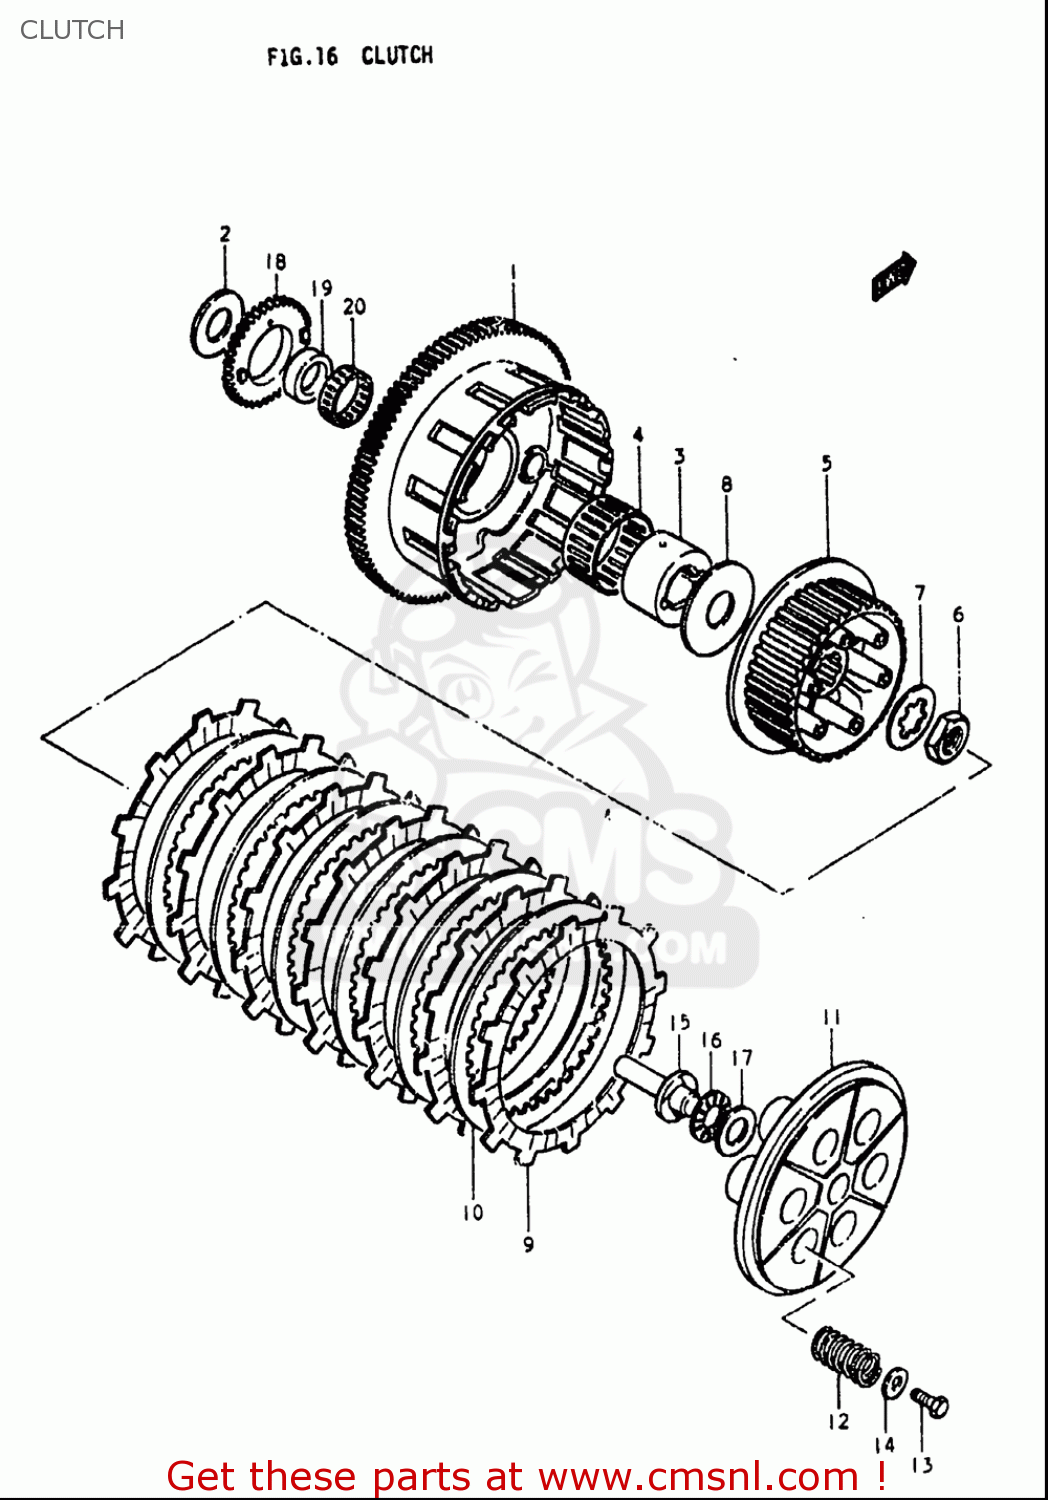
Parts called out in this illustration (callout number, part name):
2	WASHER(25X50X2.5)
3	SPACER
4	BEARING(51X56X28)
6	NUT
7	WASHER,LOCK
8	WASHER(25X66X3.5)
9	PLATE,CLUTCH DRIVE (NAS)
10	PLATE,CLUTCH DRIVEN(T:1.6) (NAS)
11	DISC,CLUTCH PRESSURE
12	SPRING
13	BOLT
14	WASHER(6.5X20X1.6)
16	BEARING(15X28X2)
17	WASHER(15.5X28X1)
18	GEAR,ENG OIL PUMP DRIVE(NT:38)
19	SPACER,OIL PUMP DRIVE GEAR
20	BEARING(36X40X10)
